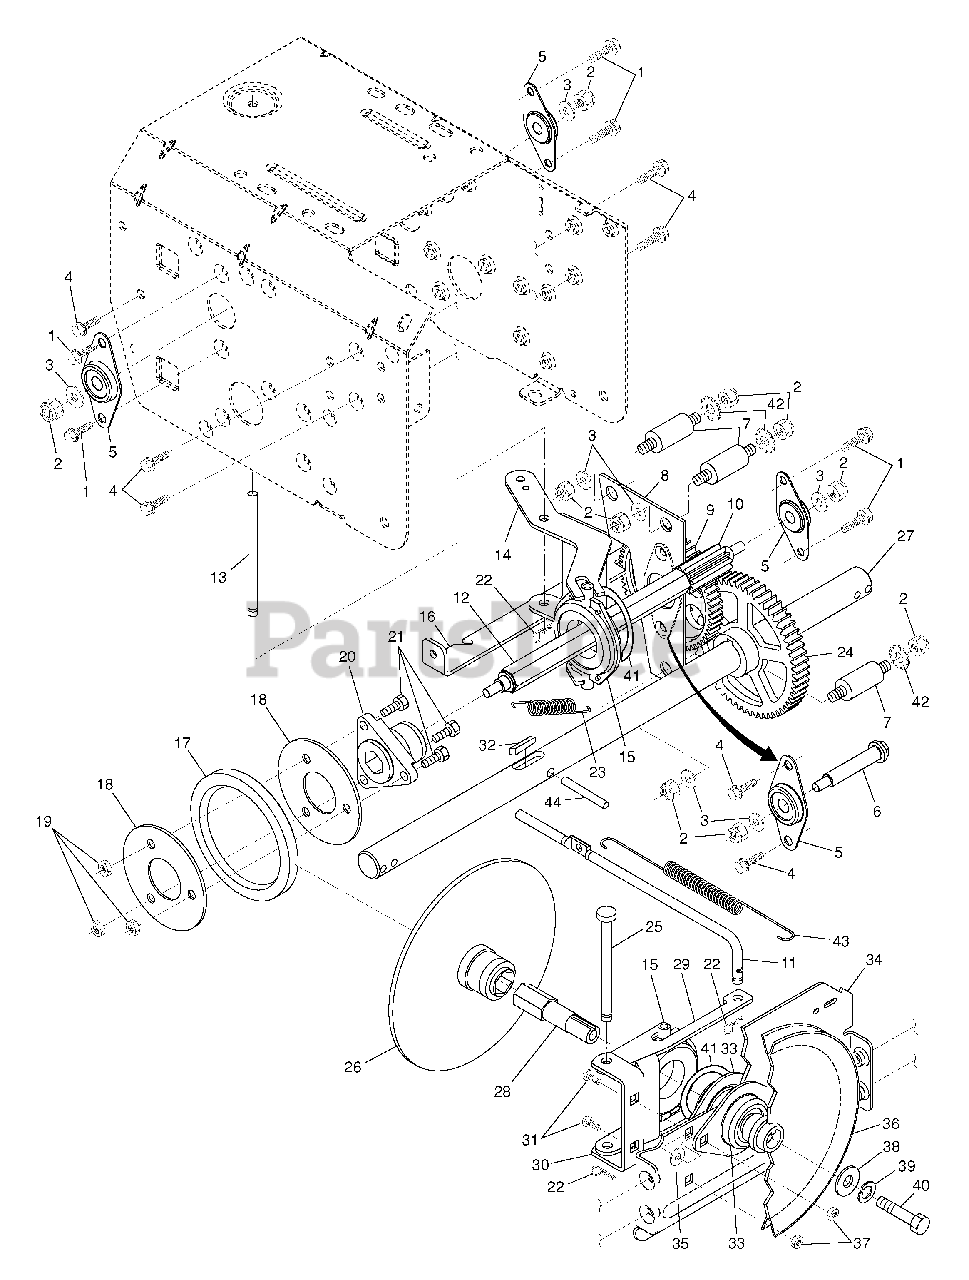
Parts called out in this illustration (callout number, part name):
1	Screw, Hex Head 5/16-18 x 5/8
2	Nut, Lock 5/16-18
3	Washer, Flat
4	Screw, Hex Head 5/16-18 x 1/2
5	Bearing, Flange
6	Shaft, Auxiliary
7	Spacer, Plate
8	Plate, Auxiliary
9	Gear, Intermediate (12/58)
10	Gear, Pinion
11	Rod, Clutch
12	Shaft, Long, Hex
13	Pin, Pivot
14	Lever, Shifter / Wheel
15	Trunnion Bearing Assembly
16	Bracket, Pivot, Shift
17	Ring, Rubber Wheel
18	Plate, Rubber Wheel
19	Nut, Lock 5/16-18
20	Hub, Rubber Wheel
21	Screw, Hex Head 5/16-18 x 7/8
22	Retainer, Hairpin
23	Spring, Bias
24	Gear, Axle (58 Teeth)
25	Pin, Pivot Lever
26	Plate Assembly, Drive
27	Shaft, Axle
28	Shaft, Short Hex
29	Lever, Shifter Plate
30	Bracket, Shifter Support
31	Bolt, Carriage 5/16-18 x 5/8
32	Key, Square
33	Bearing, Flange
34	Plate, Drive Mounting
35	Spacer, Bearing
36	Pulley, Traction Drive
37	Nut, Lock 5/16-18
38	Washer, Flat
39	Washer, Lock 5/16
40	Screw, Hex Head 5/16-18 x 3/4
41	Ring, Retaining
42	Washer, Lock, External Tooth 5/16
43	Spring, Return
